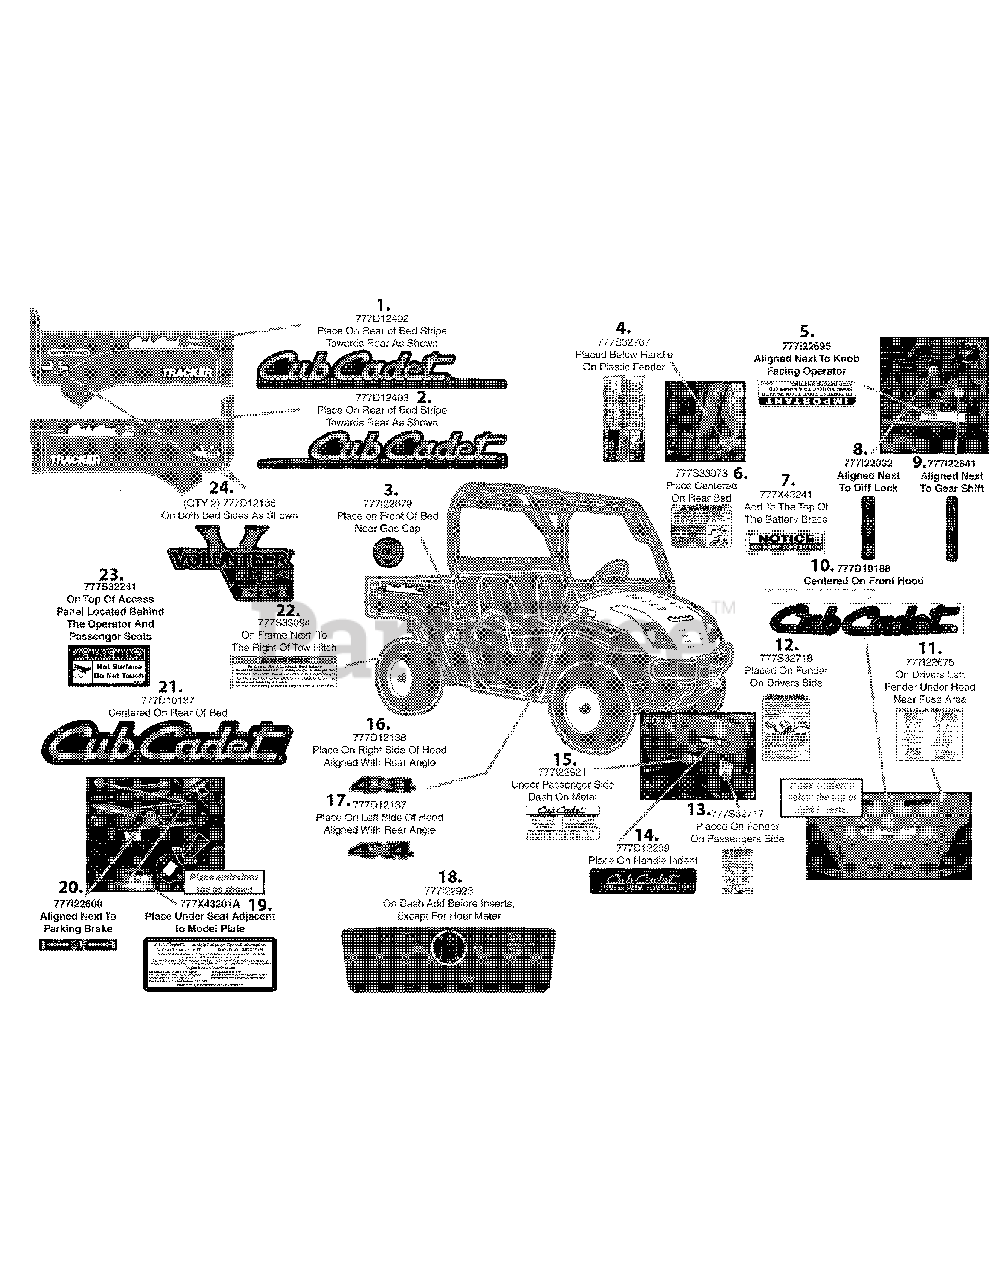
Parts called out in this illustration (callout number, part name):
1	LABEL-UV CUB CAMO EURO LH
2	LABEL-UV CUB CAMO EURO RH
3	LABEL-CHECK ENG OIL
4	LABEL-4X4 CARGO BOX HANDLE
5	LABEL:4X4 SHIFT
6	LABEL-UV 4X4 CARGO BOX
7	LABEL-DON'T JUMP BATTERY
8	LABEL-DIFF LOCK CO
9	LABEL-GEAR SHIFT
10	LABEL-CUB CADET HOOD
11	LABEL:UV:4X4 CAT FUSE
12	LABEL-ROLL & FALL LH FENDER
13	LABEL-RIDER FALL RH FENDER
14	LABEL-UV DASH LOGO CAMO
15	LABEL-UV EFI WEIGHT
16	LABEL-CUB UV 4X4 HOOD RH
17	LABEL-CUB UV 4X4 HOOD LH
18	LABEL-UV EFI DASH
19	LABEL-UV:EFI EMISSIONS
20	LABEL-PARK BRAKE
21	LABEL-CUB CADET BED
22	LABEL-SAFTEY:TOWING EFI 1400 LB
23	LABEL-HOT SURFACE
24	LABEL-UV VOLUNTEER OLIVE GREEN
